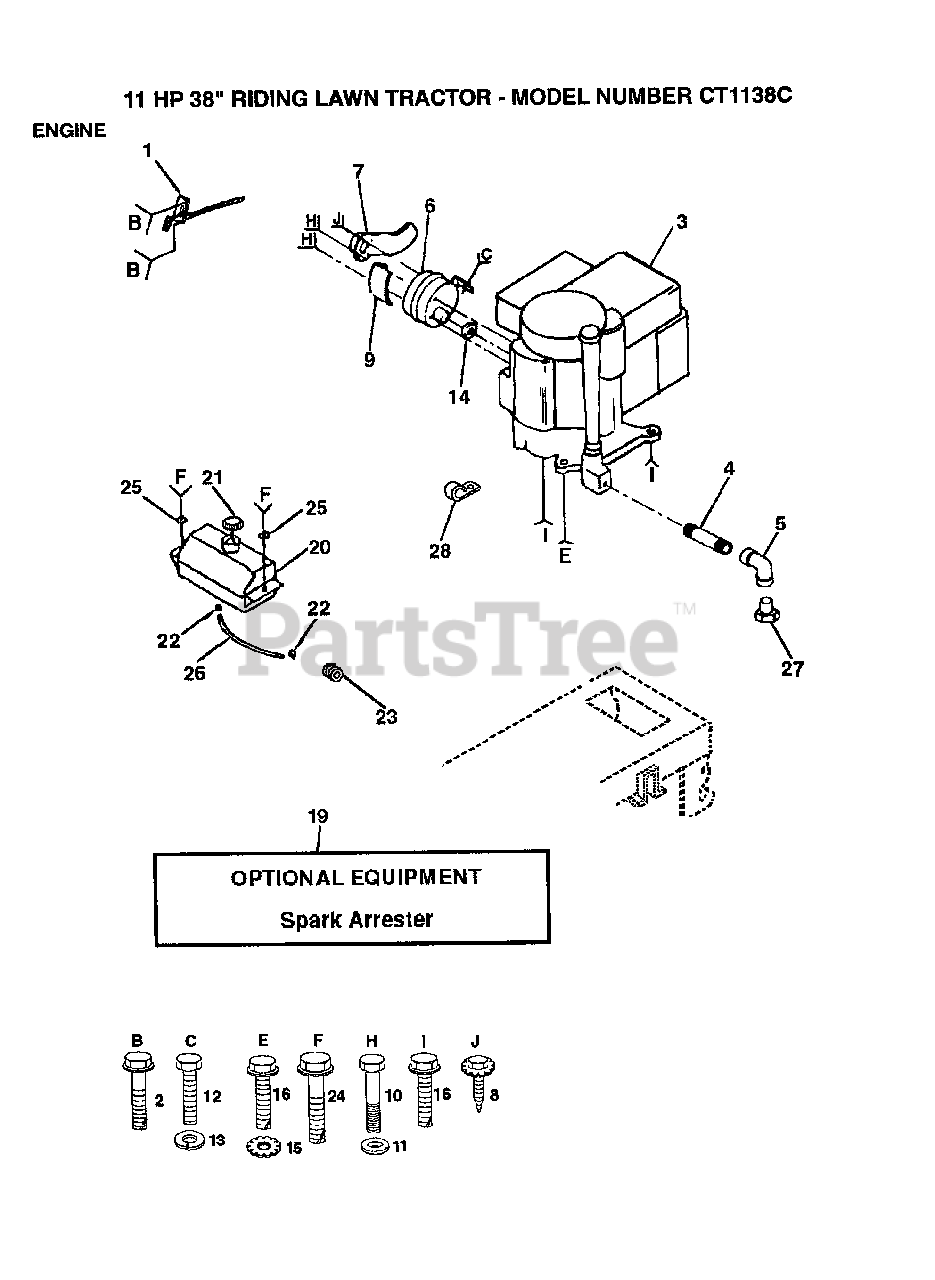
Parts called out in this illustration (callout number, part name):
1	THROTTLE CONTROL
2	SCREW LT
4	PIPE NIPPLE
5	ELBOW
6	MUFFLER LTV
7	DEFLECTOR MUFFLER
9	SHIELD HEAT LTV
10	"BOLT,HEX"
11	WASHER T
12	BOLT
13	LOCKWASHER
15	LOCKWASHER
16	SCREW
20	TANK.FUEL.LT.
22	HOSE CLAMP
24	SCREW
25	WASHER GT
26	FUEL LINE T
28	CLIP T
